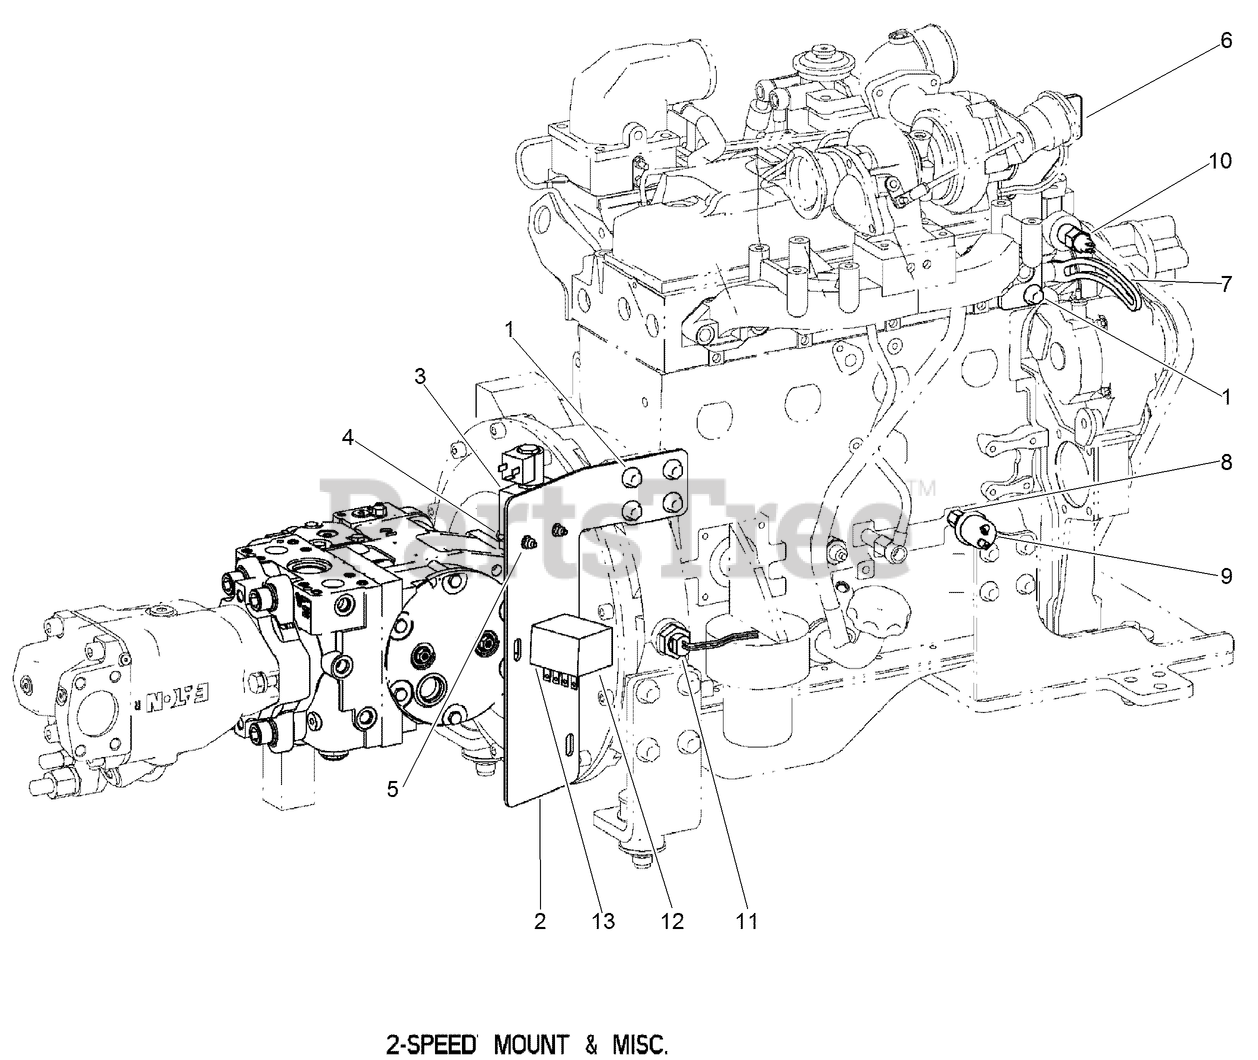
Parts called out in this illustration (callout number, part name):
1	SCREW-FLANGE
2	MOUNT - Cold Start
3	VALVE - Dir, Cart, 3W2P, SOL, 12VDC
4	SCREW, METRIC FLANGE w/BODY - M6 x 45
5	NUT, METRIC FLANGE PREVAILING - M6 Zinc
6	PLATE-HOIST POINT
7	BRACKET-Alternator
8	ADAPTER - Pipe
9	SENSOR-PRESSURE, OIL
10	SENSOR-COOLANT
11	SENSOR-RPM, MAG PICKUP
12	RELAY-CONTROL, ENGINE
13	SCREW - PHd Type 1 #10 - 24 x .500 CST ZND
